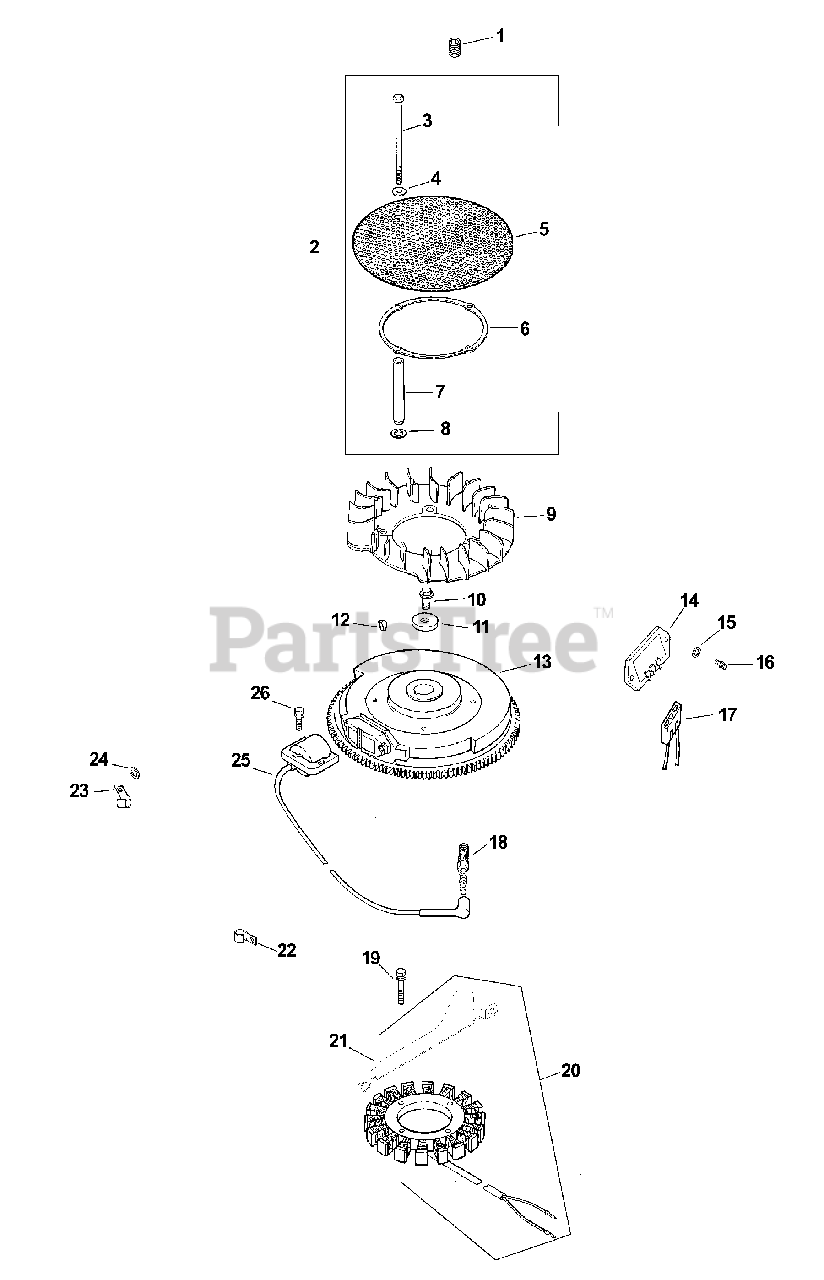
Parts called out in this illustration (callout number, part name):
1	SCREW, SKT SET #10-24X1/4"
2	KIT, CHOPPER SCREEN
3	SCREW, CAP M6X1.0X99.5
4	WASHER, FLAT 1/4" (O.D. 5/8")
5	SCREEN, GRASS
6	RING, SUPPORT USE 25 141 08-S
8	WASHER, SPRING 10 MM
9	FAN (DOMED)-USE 24 157 17-S
10	SCREW, FLG M10X1.5X45 - (#25086361S)
11	WASHER, FLAT 13/32"
12	KEY, 3/16" X 5/8"
13	FLYWHEEL, PAINTED-USE 24 025 55-S
14	REG/RECT-15 AMP (KM)-USE 41 403 10-S
15	WASHER, FLAT 3/16"
16	SCREW, PHL HD #11-16X7/8"
17	CONNECTOR, BODY (KM)-USE 25 155 41-S
18	PLUG, SPARK (STD)
19	SCREW, M5X0.8X25 - (#25086402S)
20	KIT, 15 / 20 AMP STATOR
21	BRACKET, STATOR WIRE
22	CLIP, CABLE
24	WASHER, FLAT 1/4" (O.D. 1/2")
25	KIT, MODULE IGNTN (CDI FIXED)
26	SCREW, FLG THD FRM M5X.8X20-(#25086399S)
